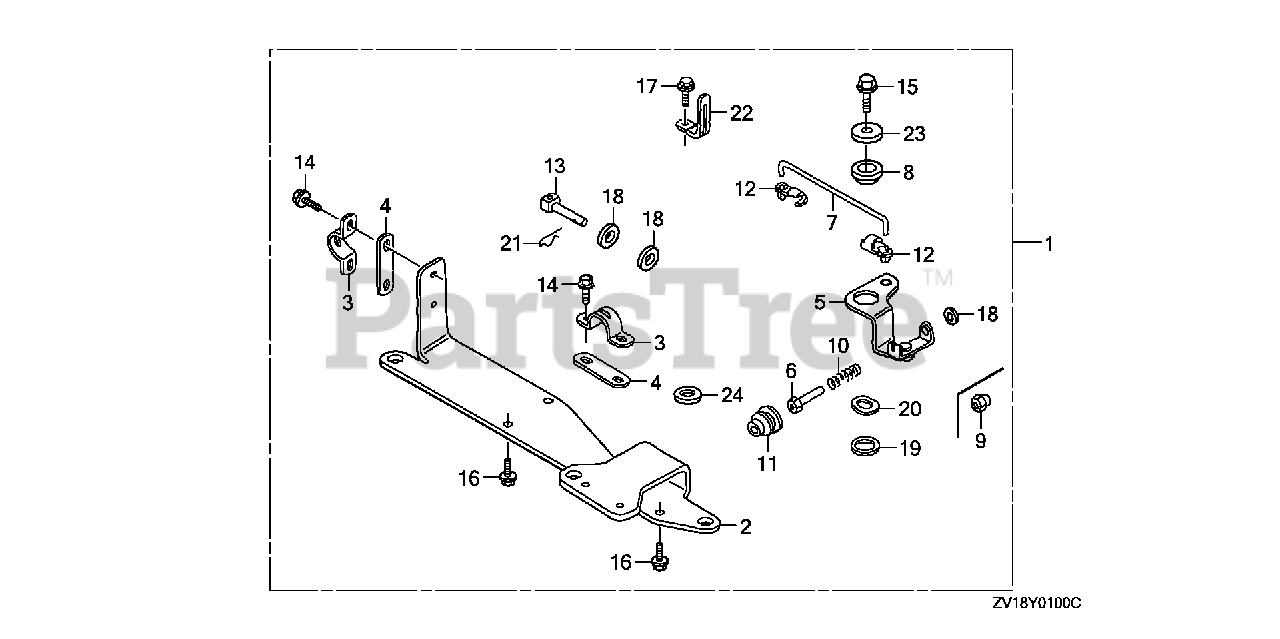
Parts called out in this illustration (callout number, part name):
1	CONTROL KIT, REMOTE
2	BRACKET, STEERING
3	CLAMP, CABLE
4	SHIM, CABLE CLAMP
5	LEVER, CONTROL
6	NUT B, CONTROL ADJUSTING
7	ROD, CONTROL
8	BUSH, CONTROL LEVER
9	NUT A, CONTROL ADJUSTING
10	SPRING, CONTROL LEVER
11	GROMMET, CONTROL CABLE
12	BUSH, LINKAGE
13	PIVOT, SHIFT
14	BOLT, FLANGE (5X10)
15	BOLT, FLANGE (6X12) (CT200)
16	BOLT, FLANGE (6X14) (CT200)
17	BOLT, FLANGE (5X10)
18	WASHER, PLAIN (5MM)
19	WASHER (14MM)
20	WASHER, WAVE (14MM)
21	PIN, LOCK (5MM)
22	CLIP B, CORD
23	WASHER, PLAIN (6MM)
24	WASHER, PLAIN (22X6X1.6)
